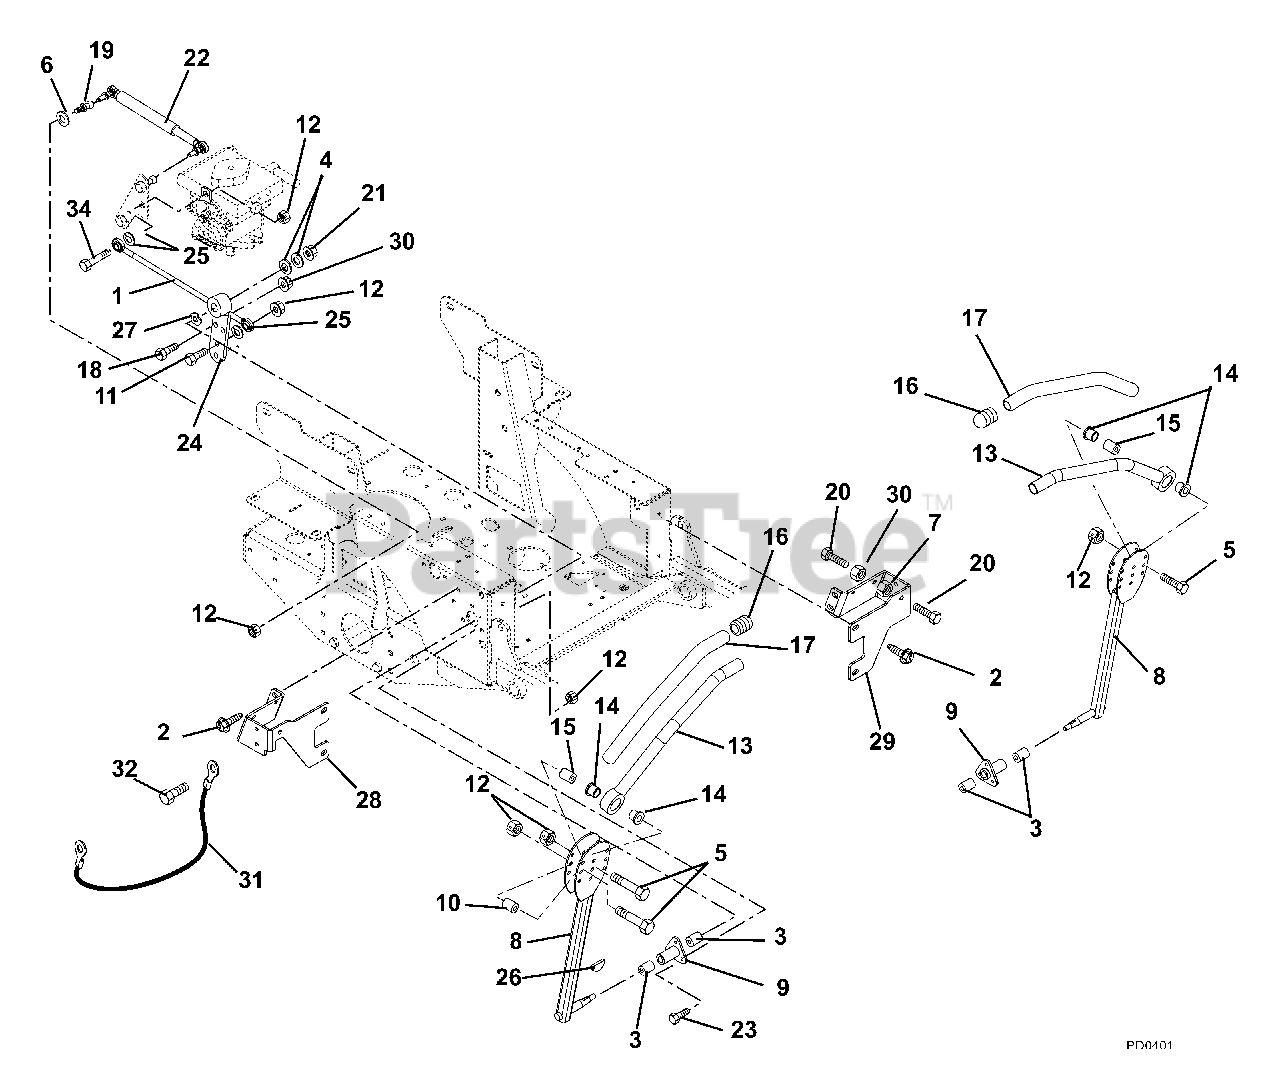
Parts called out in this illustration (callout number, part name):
1	Assembly, Steering Rod
2	Screw, Tapping .38-16 x .75 Hex Washer Head
3	Bushing .625 x .75 x .50
4	Washer, Flat Steel .406 x .812 x .065
5	Bolt, Hex .31-18 x 1.75 Grade 5
6	Washer, Flat Steel .38 x .875 x .083
7	Nut, Hex Jam .375-16
8	Control Arm
9	Housing, Bushing
10	Eccentric
11	Bolt, Hex .31-18 x 1.25 Grade 5
12	Nut, Nyloc Flange .375-16
13	Handle Weldment Left-Hand
13	Handle Weldment Right-Hand
14	Bushing, Flange Nylon .762 x 1.48 x .44
16	Caplug, Handlebar
17	Grip, Handlebar
18	Bolt, Hex .375-16 x 1.75
19	Stud, Ball
20	Bolt, Hex .38-16 x 1.25 Grade 5
21	Nut, Nyloc Flange 3/8-16
23	Bolt, Hex .31-18 x 1.00 Grade 5
24	Weldment, Pivot Arm
25	Washer, Locking .31 x .078 Regular
26	Key, Woodruff .13 x .63
27	Wave Washer
28	Stop, Steering-Right Hand
29	Stop, Steering-Left Hand
30	Nut, Locking Jam Center .375-16
31	Cable, Hood
32	Bolt-Hex .25-20 x .75 Grade 5
33	Nut, Nyloc Flange .25-20
34	Bolt, Hex .31-18 x 1.50 Grade 5
